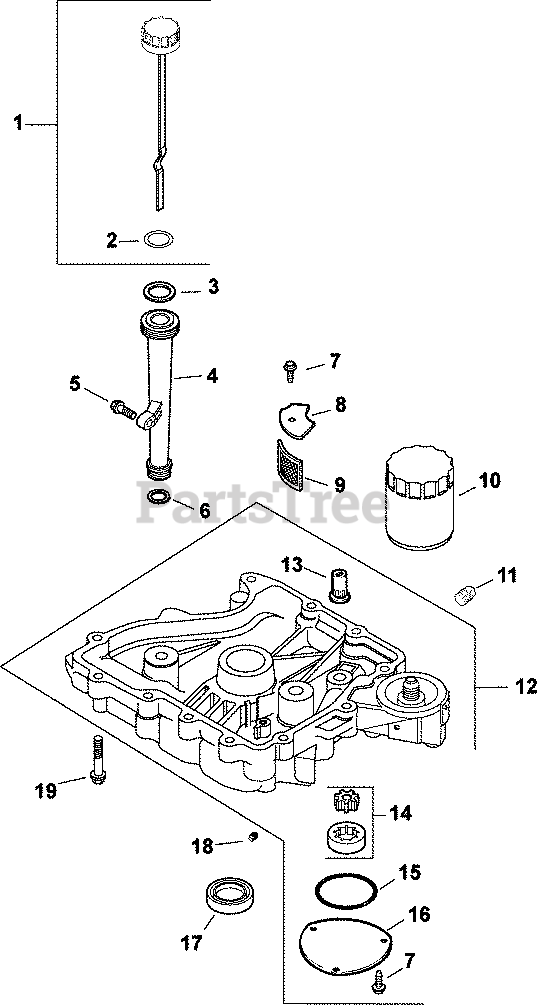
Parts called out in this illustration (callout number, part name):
1	KIT, OIL FILL CAP (YELLOW)
2	O-RING, DIPSTICK
3	O-RING, UPPER OIL FILL TUBE
4	TUBE, OIL FILL USE 25 123 07-S
5	SCREW,FLG THD FRM M6X1.0X20-(#25086396S)
6	O-RING, LOWER OIL FILL TUBE
7	SCREW,FLG THD FRM M5X0.8X16-(#25086398S)
9	SCREEN, OIL-USE 24 162 26-S
10	OIL FILTER
11	PLUG, SQ HD PIPE 3/8"
13	VALVE, OIL PRESSURE RELIEF
14	PUMP ASSEMBLY, OIL - DISCONTINUED
15	O-RING (2.5" DIA)
16	COVER, OIL PUMP
17	SEAL, OIL
18	PLUG, PIPE 1/8 NPTF-SQ.HD.
19	SCREW, FLG M8X1.25X45
